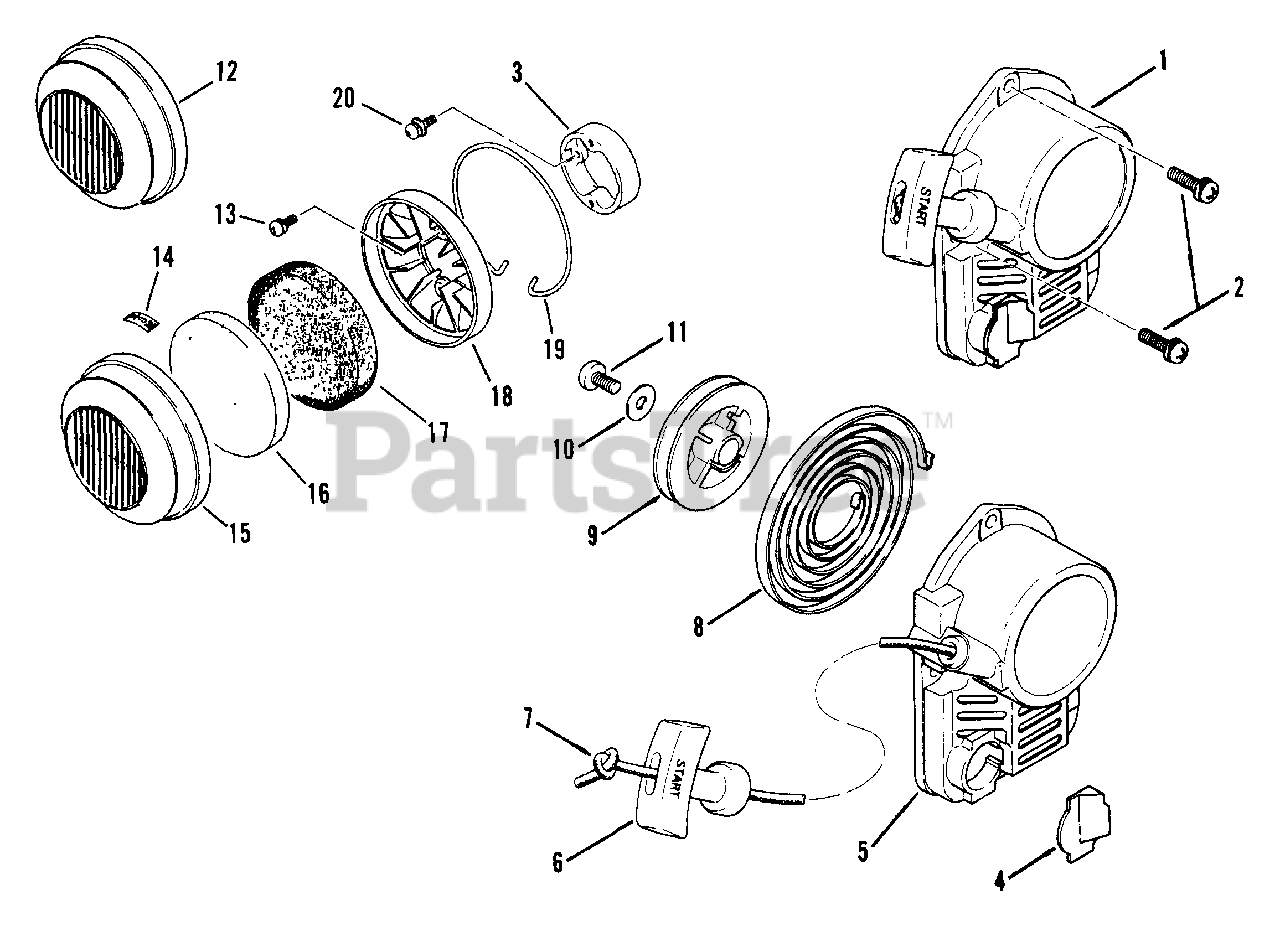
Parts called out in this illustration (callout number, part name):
1	RECOIL STARTER ASSM'Y.
2	SCREW/WASHER
5	HOUSING, Starter
6	KNOB, Starter
7	ROPE, Starter
8	SPRING, Spiral
12	ASSEMBLY, Air Cleaner
13	SCREW/WASHER
14	LABEL, Choke
15	COVER, Cleaner
16	ELEMENT, Cleaner
17	ELEMENT, Cleaner
18	CASE, Cleaner
20	SCREW/WASHER
